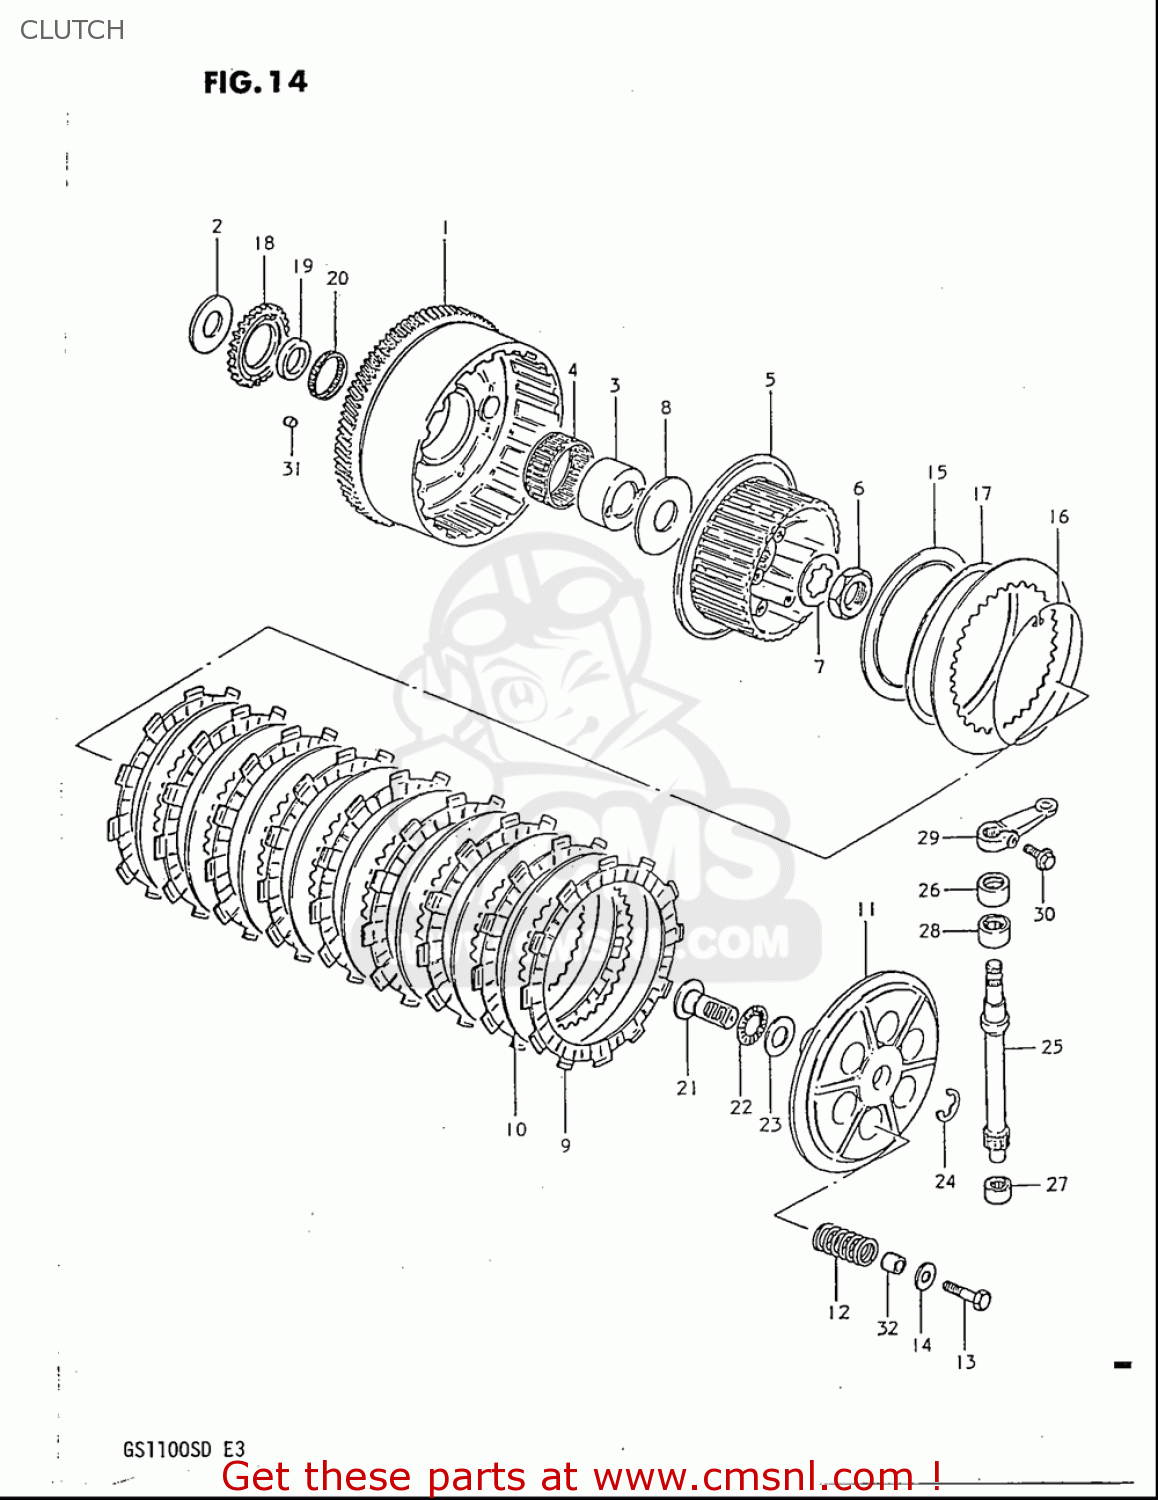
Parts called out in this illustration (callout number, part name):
1	GEAR ASSY,PRI DRIVEN
2	WASHER(25X50X2.5)
3	SPACER
4	BEARING(51X56X28)
5	HUB,CLUTCH SLEEVE
6	NUT
7	WASHER,LOCK
8	WASHER(25X66X3.5)
9	PLATE,CLUTCH DRIVE (NAS)
10	PLATE,CLUTCH DRIVEN (NAS)
11	DISC,CLUTCH PRESSURE
12	SPRING
13	BOLT
14	WASHER(6.5X20X1.6)
15	SEAT,WAVE WASHER
16	RING,STOPPER
17	WASHER
18	GEAR,ENG OIL PUMP DRIVE(NT:34)
19	SPACER,OIL PUMP DRIVE GEAR
20	BEARING(36X40X10)
21	RACK,CLUTCH RELEASE
22	BEARING(15X28X2)
23	WASHER(15.5X28X1)
24	E RING
25	PINION,CLUTCH RELEASE
26	SEAL,OIL (12X22X9)
27	BEARING(12X19X12)
28	BEARING(15X22X12)
29	ARM,CLUTCH RELEASE
30	BOLT
31	CUSHION,PRIMARY DRIVEN GEAR
32	SPACER(6.2X12X14)
